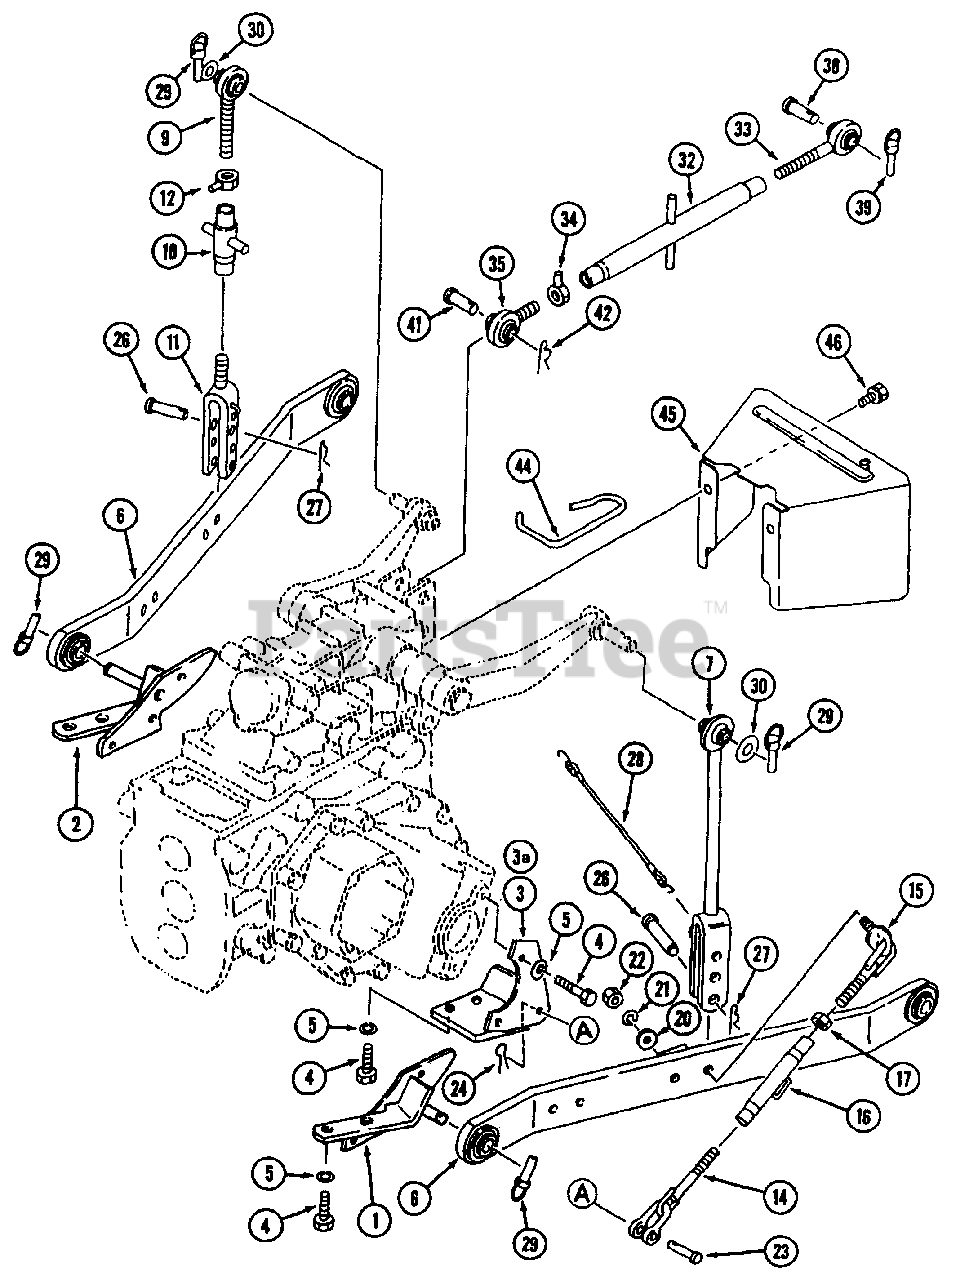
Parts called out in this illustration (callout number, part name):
7	Rod, Lift L.H.
10	Lift Rod Middle
12	Nut, Lock
20	Washer, Check Chain
29	Pin, Linch
38	Pin, Upper Link
39	Linch Pin
44	Hook, Top Link
45	Cover, PTO
